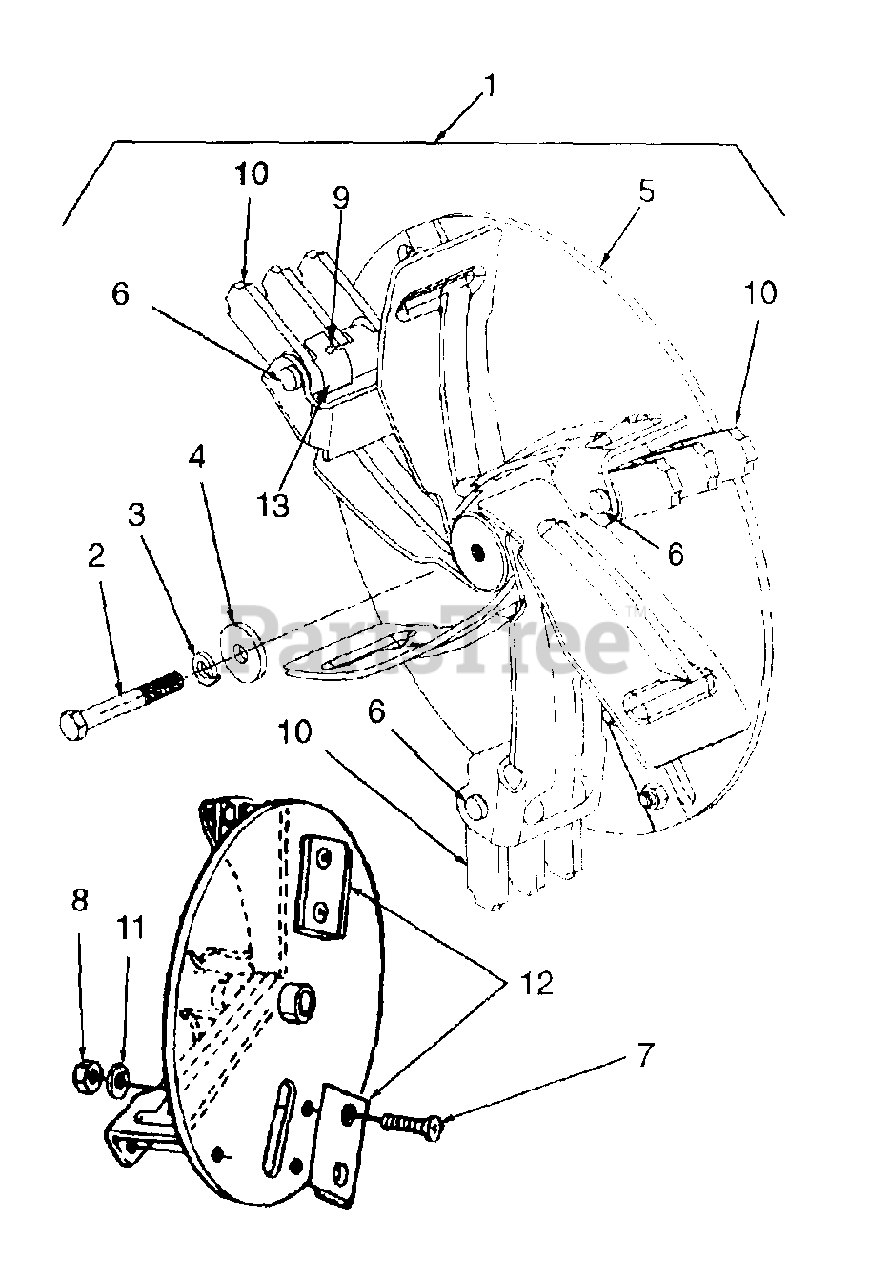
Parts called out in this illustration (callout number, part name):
1	Impeller Ass'y, Complete
2	Screw, Hex Cap, 3/8-24 x 2.75 GR5
3	Washer, Lock, 3/8 Heavy Duty 1
4	Washer, Flat, .406 x 1-1/4 HD1
5	Impeller Assembly
6	Pin, Clevis
7	Screw, Flat Hd. Cap, 5/16-24 x 1.0
8	Nut, Hex Insert Lock, 5/16-24
9	Pin, Spirol, 5/32 x 1.125
10	Blade, Flail
11	Washer, Lock, 5/16
12	Blade, Chipper
13	Pin Retaining Clip
